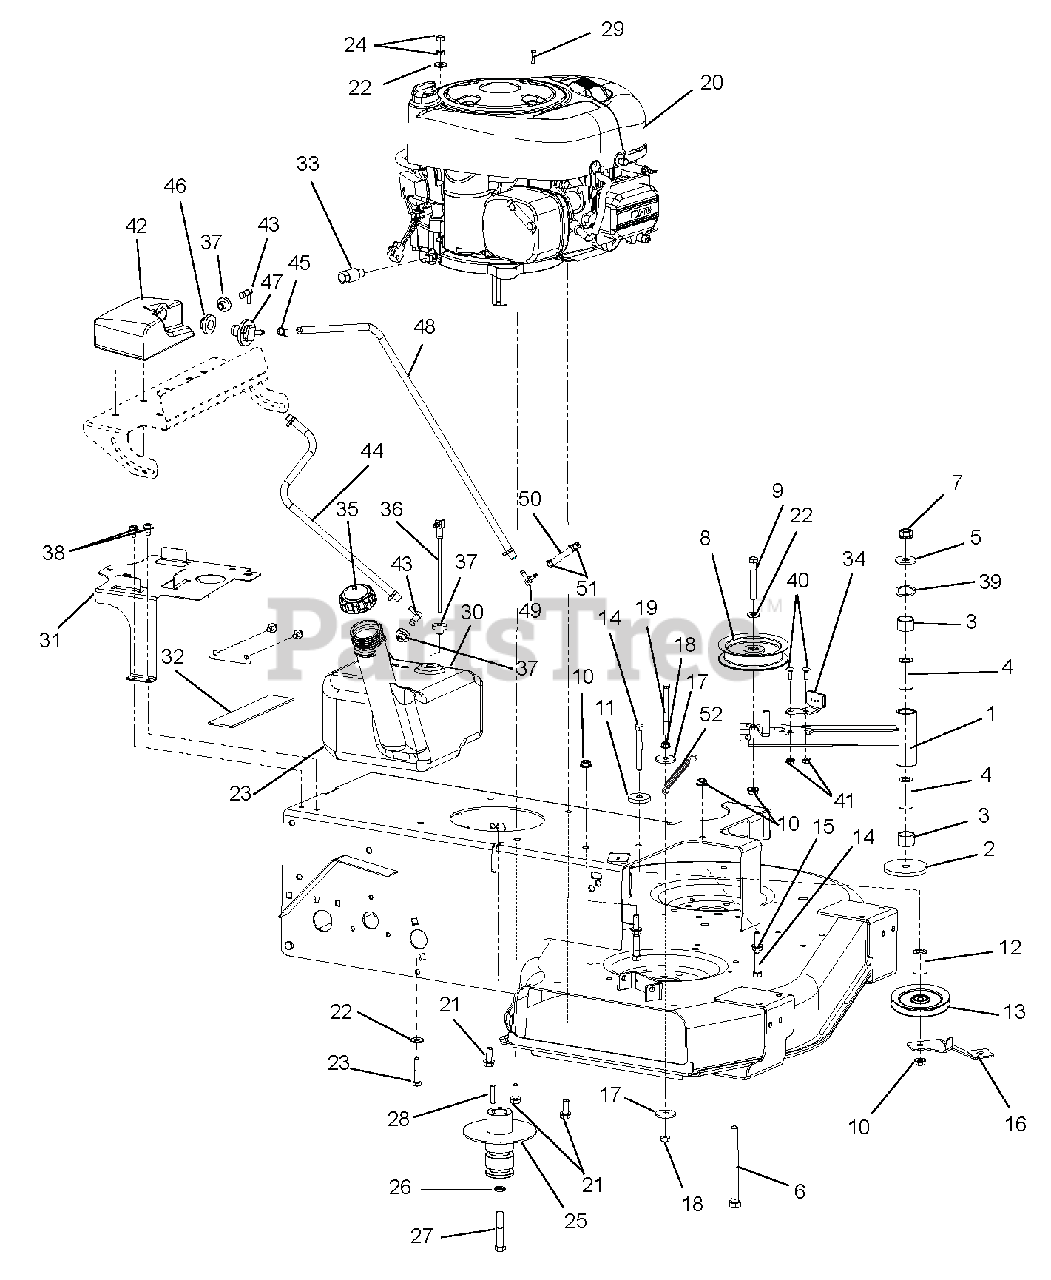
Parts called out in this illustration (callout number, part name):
1	WLDMT, PTO IDLER ARM
2	WASHER, FLAT .531X3.000X.25
3	BRG, 1.00 X 1.12 X .75
4	BSHG, SPCR .502X.997X2.03 PM
5	WSHR-FL-STL.511X1.441X.125 YWZ
6	@BLT-HEX .50-13X5.50 GR5YWZC
7	@NUT-LK-TOP-FLG .50-13 YWZC
8	ASM, IDLER 4"
9	@BLT-HEX .38-16X2.75 GR5 YWZC
10	@NUT-LK-TOP-FLG .38-16 YWZC
11	WSHR,FLT STL.406X1.50X.245YWZC
12	SPACER, .437X1.0X1.23
13	SHV, .38"ID X 4.00"OD V-IDLER
14	@BLT-HEX .38-16X3.00 GR5 YWZC
15	@NUT-SPNLK-FLG .375-16 YWZC
16	BRKT-IDLER BRACE
17	WSHR-FL-STL .406X1.375X.135 YZ
18	@NUT-SPNLK-FLG .312-18 YWZC
19	@BLT-HEX .31-18X3.50 GR5 YWZC
20	ENGINE, B&S 14.5 POWERBUILT
21	@SCR-TAP .38-16X1.00 HWH TR YZ
22	@WSHR-FL-STL.38X.875X.083 YWZC
23	@BLT-HEX .31-18X1.75 GR5 YWZC
24	@NUT-LK-CTR .31-18 YWZC
25	PULLEY, PRO-GROUND DRIVE
26	@WSHR-LK .44X.109 REG YWZC
27	BLT-HEX .44-20X2.50 G5 YZ EP80
28	KEY-SQ .25 X 1.25 X .25 SAE
30	TANK, ZOOM/WAW NON-PERM. FUEL
31	BRKT, GAS TANK MOUNT
32	PAD, GAS TANK
33	DRAIN, OIL
34	BRAKE PAD ASSY WAW
35	CAP, 2.25" ONE-WAY VENT FUEL
36	ASSY-PICKUP, FUEL 6.5L
37	BSHG-FLG .375X1.062X.625 NITR
38	@SCR-TAP .31-18X.50 HWH TR YWZ
39	WASHER - WAVE 1.09X1.37X.016
40	@BLT-RDHDSQNK .25-20X.75 G5YZ
41	@NUT-LK-TOP-FLG .25-20 YWZC
42	TANK, FUEL EXPANSION
43	FITTING, STRAIGHT FUEL PLASTIC
44	HOSE, .25 LOW-PERM BULK GAS
45	CLAMP-HOSE WIRE .490/.510X.116
46	GROMMET, REMOTE VENT NITRILE
47	VENT, ROLL-OVER (.25"ID HOSE)
48	HOSE, .25 LOW-PERM BULK GAS
49	FITTING-3/16X1/4 90DEGREE VAC
50	HOSE, .188 LOW-PERM BULK GAS
51	CLAMP-HOSE, SPRING .188
52	SPRING - ENGINE - TRANS.
